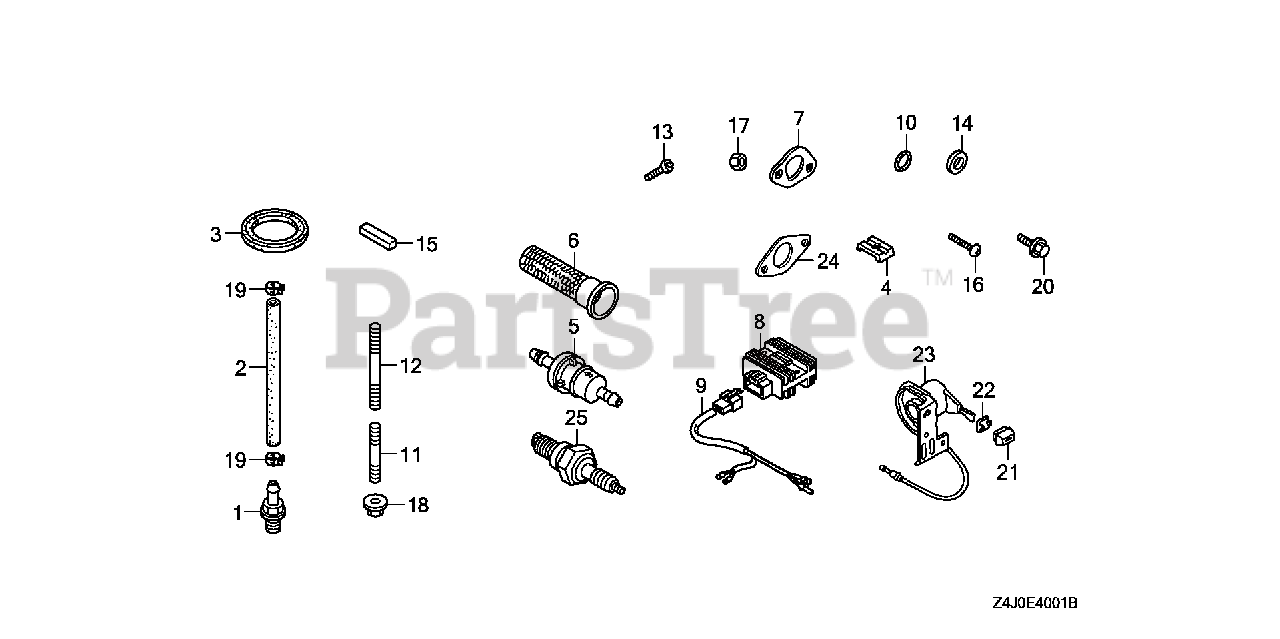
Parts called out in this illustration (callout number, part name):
5	FILTER, FUEL
6	ARRESTER, SPARK
7	GASKET, MUFFLER
17	NUT, HEX. (8MM)
